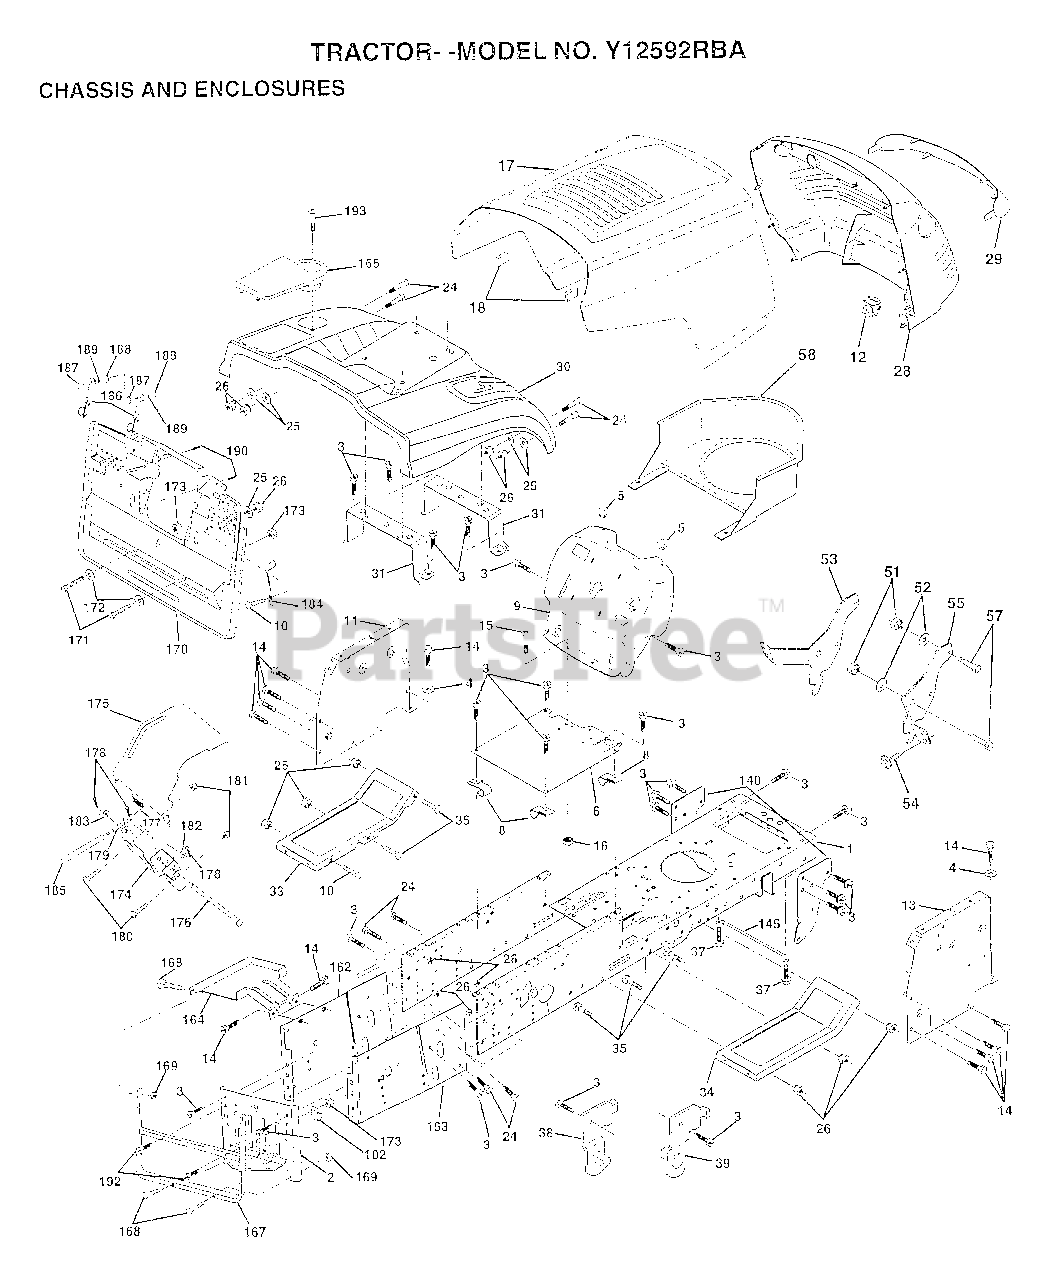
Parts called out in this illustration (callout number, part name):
1	CHASSIS.STAMPING
2	DRAWBAR.CRD
3	SCREW
4	WASHER
5	BUMPER-HOOD/DASH
6	SADDLE
8	"CLIP,INSULATOR"
9	DASH.SILKSCREEN
11	"PANEL-DASH,LH"
12	CLIP.TINNERMAN
14	SCREW LT
15	SCREW
17	HOOD.STEEL.ASSY
24	BOLT
25	WASHER
26	NUT
28	GRILLE-MS428
29	LENS.GRILLE.PRIVATE LABEL
30	FENDER.FEAR.CRD.RED
31	BRKT.SUPT.FENDER.CRD
33	FOOTREST.LH.LT/GT
34	FOOTREST.RH.LT/GT
35	BOLT
37	SCREW LT
38	BRACKET ASM LH
39	BRACKET ASM RH
51	NUT
52	WASHER
53	BRACKET.GRILLE.LH
54	SCREW.HEX.WS.HD
55	BRACKET.GRILLE.RH
58	AIR DUCT
102	CLIP T
140	BRKT SUSPENSION
145	"ROD POVOT,CHASSIS"
162	BRKT.EXT.CHASSIS.LH.CRD
163	BRKT.EXT.CHASSIS.RH.CRD
164	SUPPORT.BATTERY.CRD
165	COVER.BATTERY.CRD.BLACK.LT
167	SUPT.ASM.BACKPLATE
168	BOLT-RD HD SQ NK
170	COVER.BACKPLATE.BLACK
171	BOLT.HEX.3/8-16X2-1/2
173	NUT
174	BRKT.SWITCH.FBI.CRD
175	GRUARD.DOOR.REAR.CRD
176	HINGE PIN
177	SPRING.COVER.LH
179	ROD.PIVOT.FBI.CRD
182	WASHER.385X.625
183	WASHER
184	BRKT.ACTUATOR.BAG.CRD
185	TUBE.LEVER.SWCH.FBI.CRD
186	LATCH ASSY.BAGGER
187	WELDNUT
188	WASHER #10
189	LOCKWASHER
190	SCREW
192	SCREW LT
193	SCREW LT
